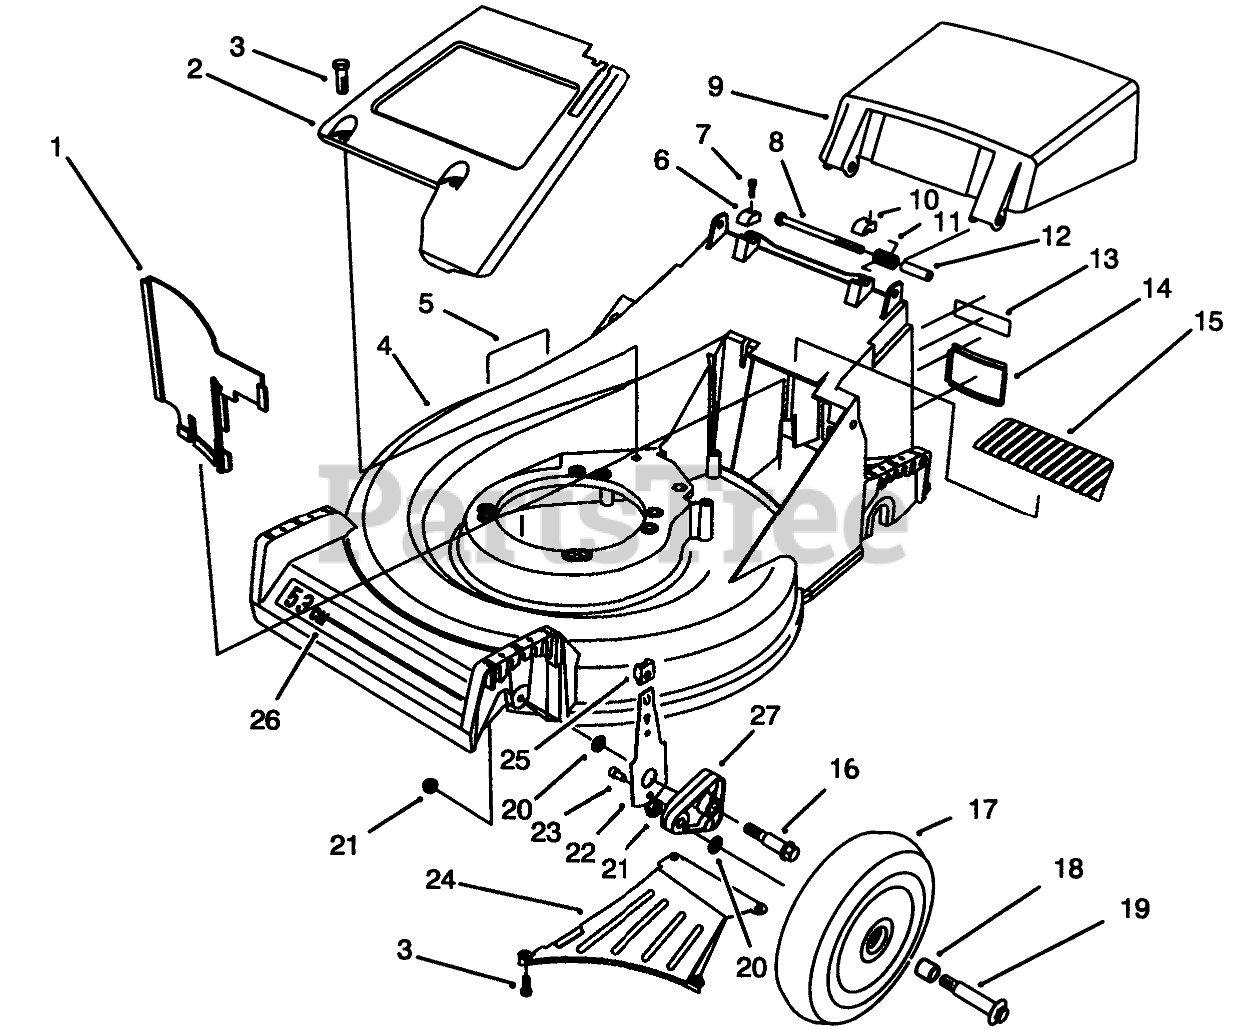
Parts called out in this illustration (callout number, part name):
1	PANEL-VERTICAL
2	PaneI-Screen
3	SCREW-HWHTF
4	Housing-53cm (Incl. Ref. #5 & 26)
5	Decal Danger
6	CAP-HINGE BOLT, RH
7	SCREW-HSH
8	SCREW-HH
9	Door Discharge
10	CAP-HINGE BOLT, LH
11	SPRING-DOOR
12	SPACER-DOOR
13	DECAL FRENCH REGUL.
14	COVER-ACCESS
15	COVER-TOP
16	BOLT-SHOULDER
17	Wheel & Tire Assembly (Incl. Ref. #21)
18	BUSHING
19	WHEEL BOLT
20	WASHER
21	NUT-LOCK
22	FRONT SPRING ARM ASM
23	SCREW-HSH, THREAD FORMING
24	Ramp-Discharge
25	KNOB-ARM
26	DECAL
27	ARM-PIVOT, FRONT
